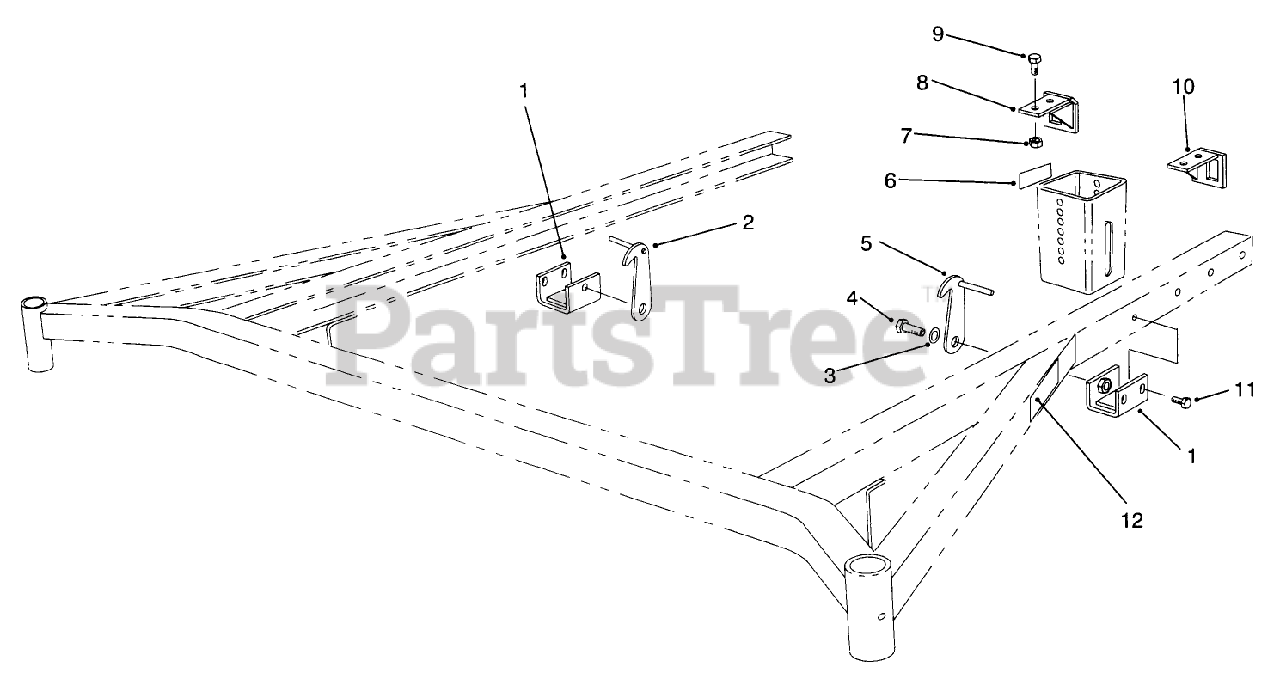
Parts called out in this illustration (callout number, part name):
1	BRACKET WA - LATCH R
2	Retainer-Deck, RH
3	WASHER-SPRING
4	SCREW-HH
5	Retainer-Deck, LH
6	DECAL-WARNING
7	NUT-LOCK, SIDE
8	Bracket-Deck, RH
9	SCREW-HH
10	Bracket-Deck, LH
11	SCREW-HWH
12	DECAL-HOC
